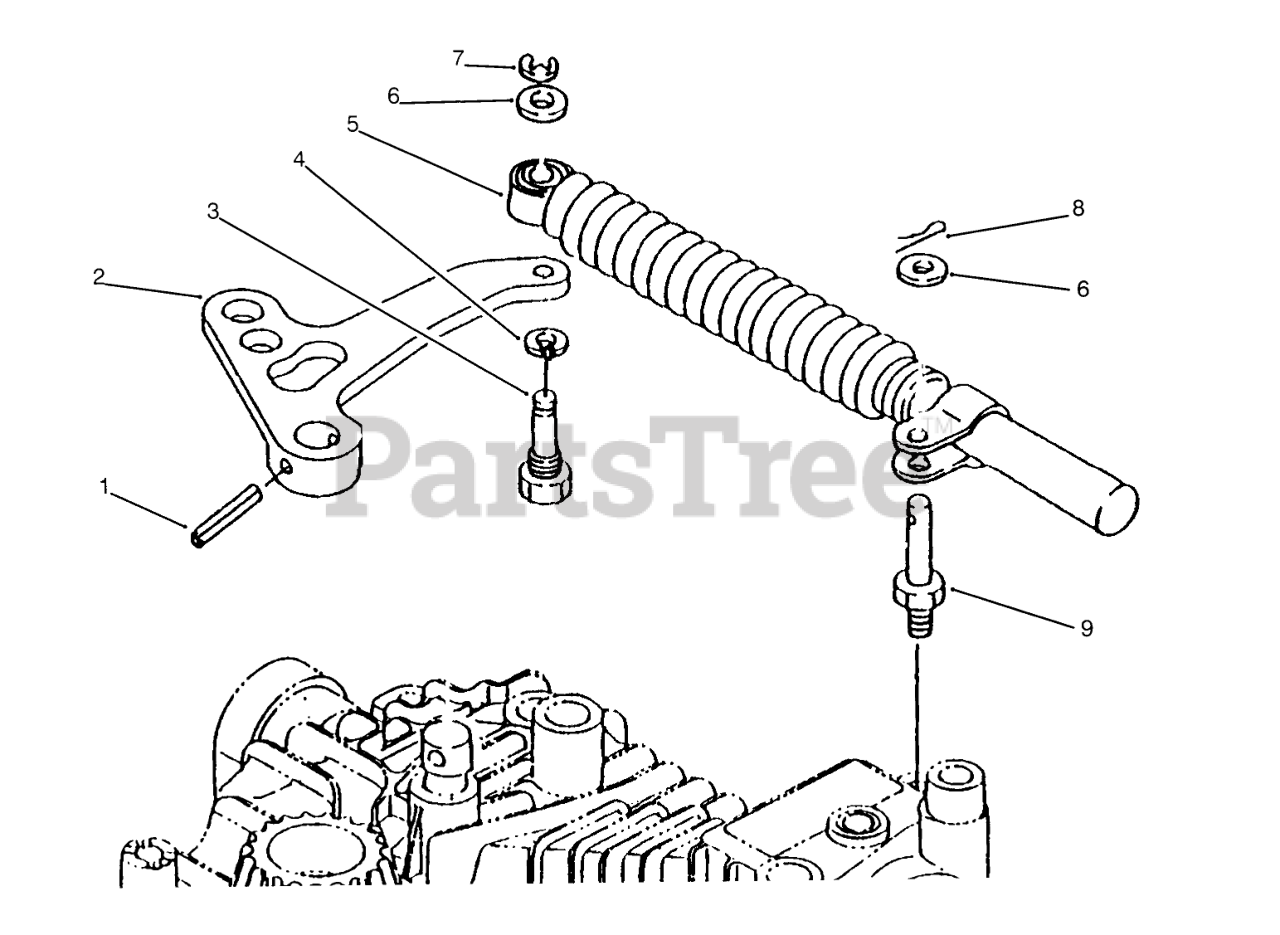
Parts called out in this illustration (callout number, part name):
1	Pin-Roll (Only On: 72043,72063,72103)
2	Arm (Only On: 72043,72063,72103)
3	Bolt (Only On: 72043,72063,72103)
4	Washer (Only On: 72043,72063,72103)
5	Shock Absorber (Only On: 72043,72063,72103)
6	Washer (Only On: 72043,72063,72103)
7	Ring (Only On: 72043,72063,72103)
8	Pin-Cotter (Only On: 72043,72063,72103)
9	Stud (Only On: 72043,72063,72103)
